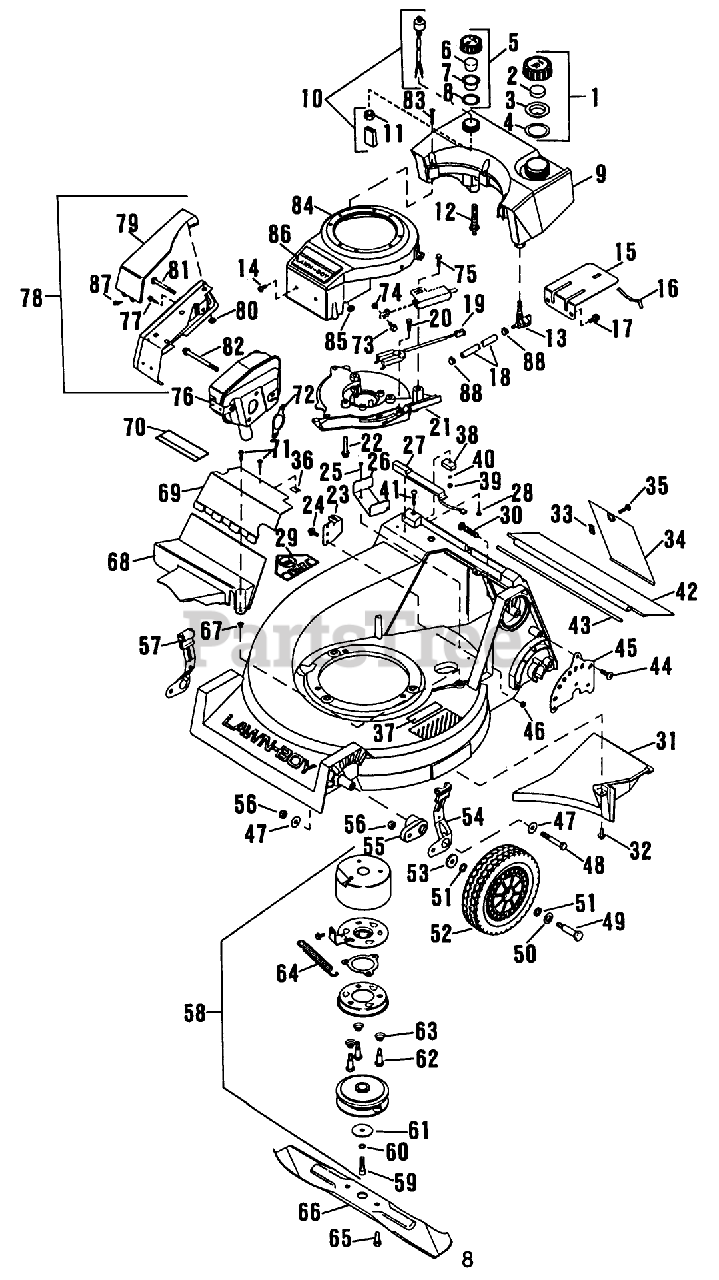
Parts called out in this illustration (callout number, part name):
1	CAP AY - FUEL M
2	BAFFLE - FOAM SM
4	GASKET-FUELCAP SM
5	CAP AY. OIL M
6	FILTER S
14	DISC/LB SER.BUL.#6
15	DISC. LB SER.BUL.#6
16	SPRING
18	GAS LINE SM
19	SWITCH INT.LOCK S
22	SCREW-SEMS F
27	SWITCH AY DELTA
31	CHUTE BAFFLE NYL
33	SPEED NUT LARSON
34	DOOR-ACCESS ELECT.
35	SCREW-CROSS RECESS
36	NUT-SPEED
44	SCREW-BHTF
45	PLATE HGT CMS
46	LOCKNUT E
47	WASHER-PLAIN
50	SPACER
51	WASHER
52	WHEEL&TIRE 8" TRI
53	WASHER
54	KNOB & SPRING CMS
56	NUT-JAM, LOCKING
57	KNOB & SPRING CMS
61	WASHER
62	SCREW,SHOULDER SM
64	SPRING
65	SCREW SEMS
66	21" Blade
67	NUT-CLIP
71	SCREW S
72	GASKET - EXH SM
74	LOCKNUT E
75	SCREW-HH
77	SCREW S
78	MUFFLER GUARD AY
79	COVER MUFFLER CP
80	NUT-PUSH
81	SCREW SM
82	SCREW-SEMS
83	DISC.LB SER.BUL.#6
85	NUT-PUSH
87	SCREW SM
88	HOSE CLAMP SM
